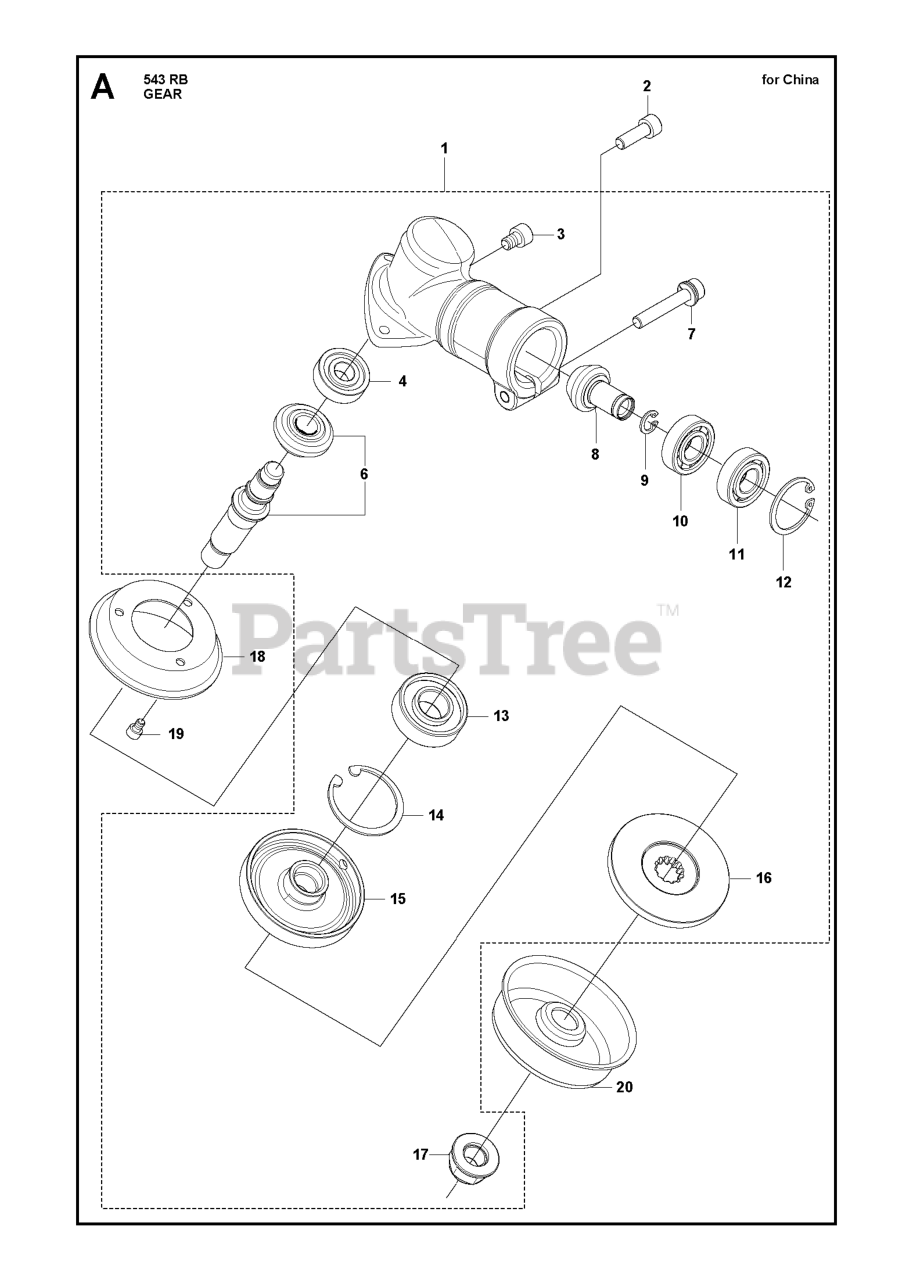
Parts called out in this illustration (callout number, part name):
9	RING, SNAP, M10 x 1.0
12	RING,SNAP M26x1.2 RP-318013340
13	BEARING***
14	RING
15	HOLDER(A)
16	HOLDER(B)
17	NUT
19	BOLT M5X8 T27 10.9
20	COVER
